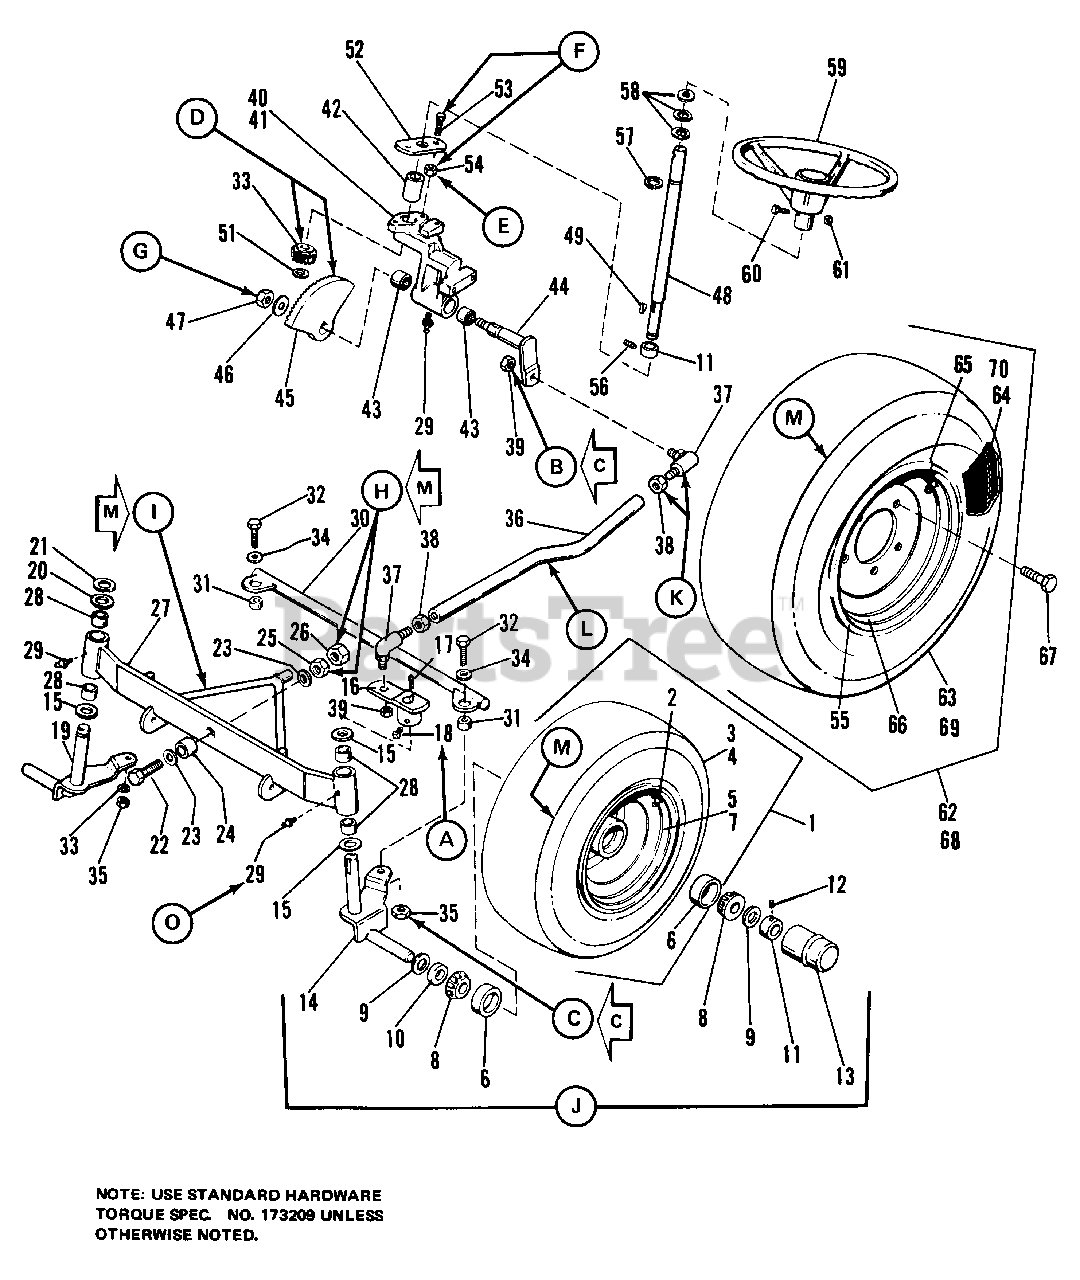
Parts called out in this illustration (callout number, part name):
1	WHEEL & TIRE ASSEMBLY
2	VALVE STEM & CAP
3	TIRE, 16-6.50 x 8
4	TUBE, 16-6.50 x 8
5	WHEEL ASSEMBLY
6	CUP, Bearing
8	CONE, Bearing
11	COLLAR, Set
12	SETSCREW, Sq. Hd., Cup Pt., 5/16-18 x 5/16
13	CAP, Hub
14	SPINDLE ASSY, L.H.
16	ARM, Steering, L.H.
17	KEY, Square
18	SETSCREW, 5/16-18 x 1/2
19	SPINDLE ASSY, R.H.
21	RING, Retaining, No. 75
22	CAPSCREW, Hex Hd., 1/2-13 x 2-1/4
23	WASHER, Plain, 1/2
25	LOCKNUT, Hex, 1/2-13
26	NUT, Jam Hex, 1/2-13
27	FRONT AXLE ASSY
29	FITTING, Grease
30	TIE ROD ASSY
32	CAPSCREW, Hex Hd., 3/8-16 x 1-1/4
33	PINION, Bevel
34	WASHER, Plain, 3/8
35	LOCKNUT, Hex, 3/8-16
36	LINK, Drag
37	JOINT, Ball
38	NUT, Jam Hex, 1/2-20
39	LOCKNUT, Hex, 1/2-20
40	STEERING HOUSING ASSEMBLY
41	HOUSING, Steering
43	BEARING, Needle
44	STEERING ARM ASSEMBLY
45	GEAR, Bevel
46	WASHER, Plain, 7/16
47	LOCKNUT, Hex, 7/16-14
48	SHAFT, Steering
49	KEY, Woodruff, No. 6, 5/32 x 5/8
51	"E" RING
52	PLATE, Steering
53	CAPSCREW, Hex Hd., 3/8-16 x 1-1/4
54	LOCKNUT, 3/8-16
55	WHEEL DRIVE
56	SETSCREW, Sq. Hd., 5/16-18 x 1/4
57	RING, Retaining
59	WHEEL, Steering
60	CAPSCREW, Hex Hd., 5/16-18 x 1-1/4
61	LOCKNUT, Flange, 5/16-18
62	WHEEL & TIRE ASSEMBLY, 23-10.50 x 12
63	TIRE 23-8.50 x 12
64	TUBE, 23-8.50 x 12
65	STEM & VALVE CAP
66	WHEEL, Drive
68	WHEEL & TIRE ASSEMBLY 23-10.50 x 12
69	TIRE, 23-10.50 x 12
70	TUBE, 23-10.50 x 12
